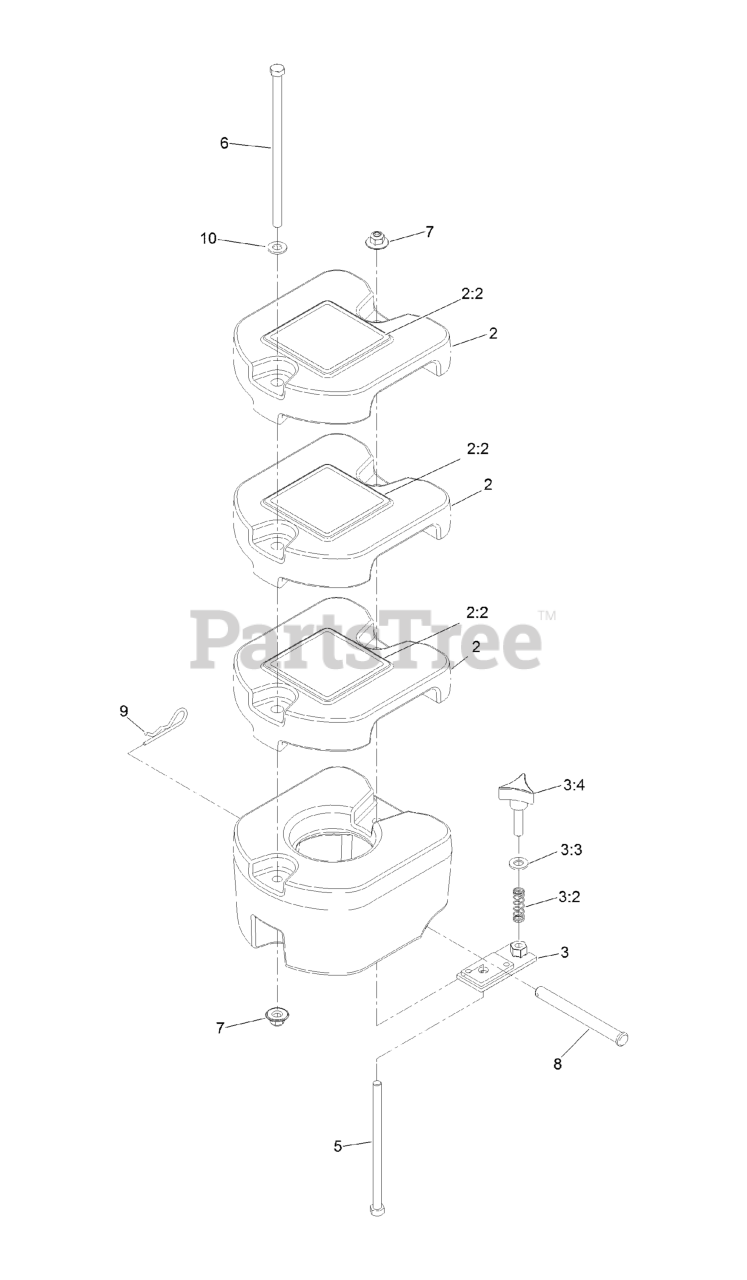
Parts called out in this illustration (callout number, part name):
2	WEIGHT-20LB
2:2	DECAL-WARNING, TRACTION
3	CASTER WEIGHT BRACKET ASM
3:3	WASHER-FLAT
5	SCREW-HH
6	SCREW-HH
7	Nut-Nyloc 3/8-16 Flg
8	PIN-CLEVIS
9	PIN-COTTER
10	WASHER-FLAT
